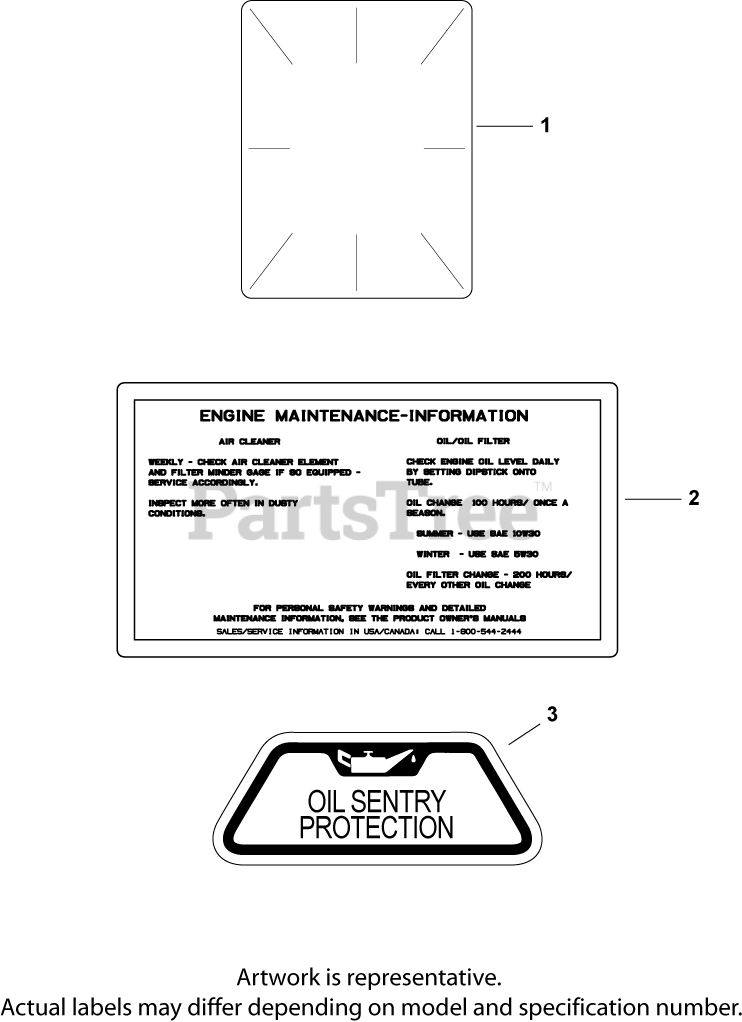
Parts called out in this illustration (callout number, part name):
1	DECAL, CLEAR LAMINATE USE 25 113 70-S
2	DECAL, AIR CLEANER - (#DSC)
3	DECAL, OIL SENTRY - (#DSC)
